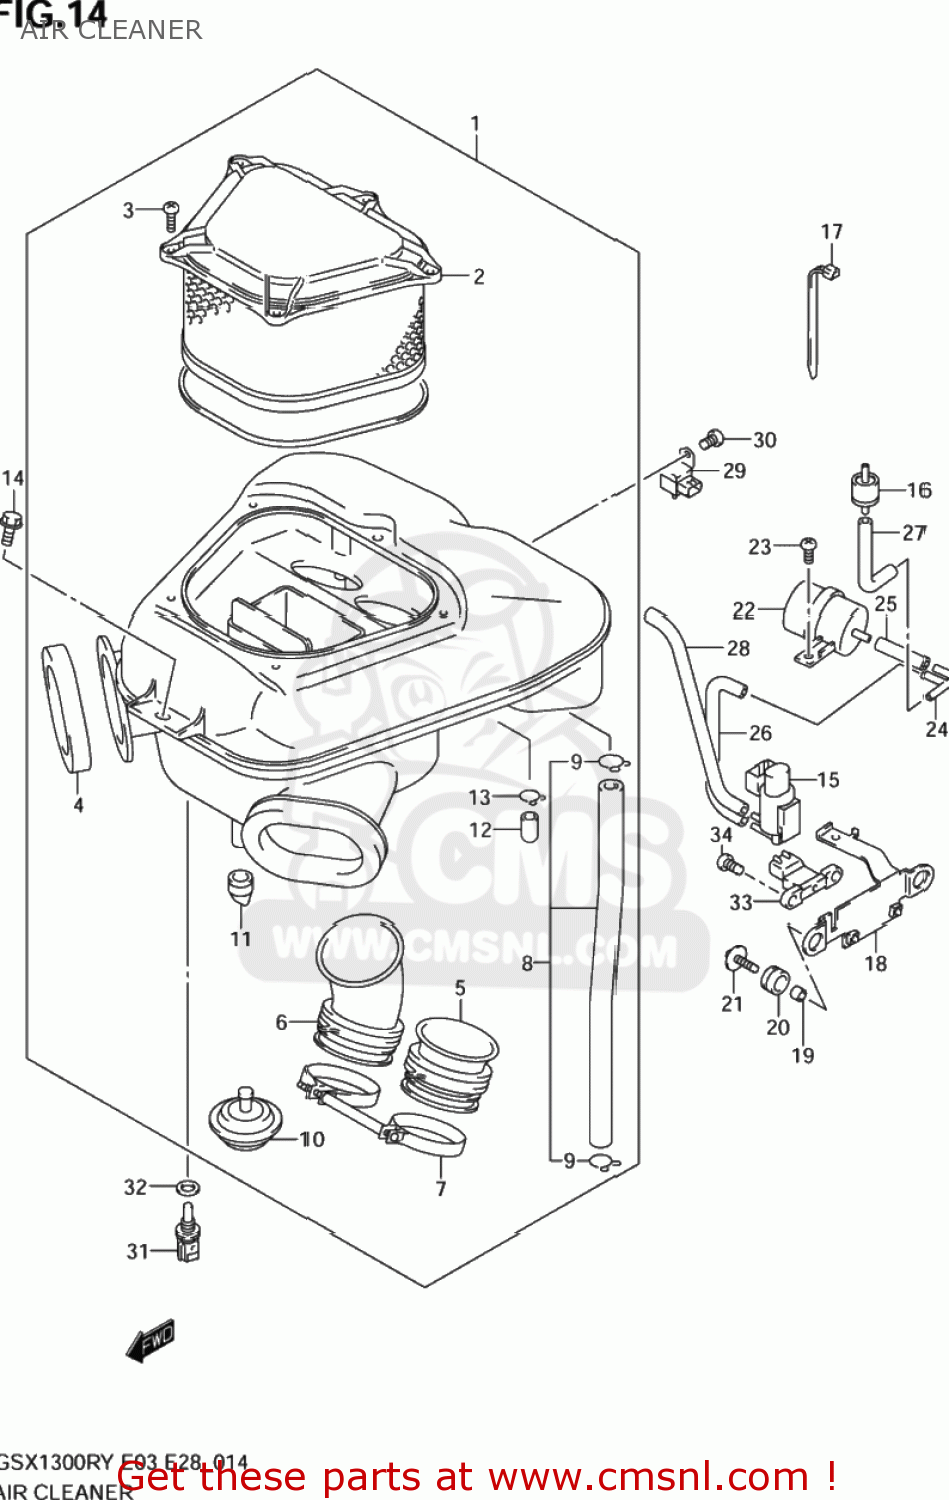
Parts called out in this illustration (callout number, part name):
1	CLEANER ASSEMBLY,AIR
2	FILTER ASSEMBLY,AIR CLEANER
3	SCREW,AIR CLEANER
4	CUSHION,DUCT
5	TUBE,OUTLET
6	TUBE,OUTLET
7	CLAMP
8	TUBE,BREATHER
9	CLIP
10	DIAPHRAGM,CONTROL VALVE
11	CAP,DRAIN
12	PLUG
13	CLIP
14	BOLT(6X16)
15	VALVE ASSY,3WAY SOLENOID
16	VALVE,CHECK
17	CLAMP(L:125)
18	BRACKET,SOLENOID VALVE
19	SPACER(6.5X9X6.5)
20	CUSHION
21	BOLT(6X20)
22	CHAMBER,VACUUM
23	SCREW 5X12
24	JOINT
25	HOSE(4X8X600)
26	HOSE(4X8X600)
27	HOSE(4X8X600)
28	HOSE(4X8X600)
29	SENSOR,BOOST
30	SCREW 6X10
31	SENSOR,WATER TEMP
32	GASKET(12X17X1) (NAS)
33	SENSOR,MAP
34	SCREW 6X12
